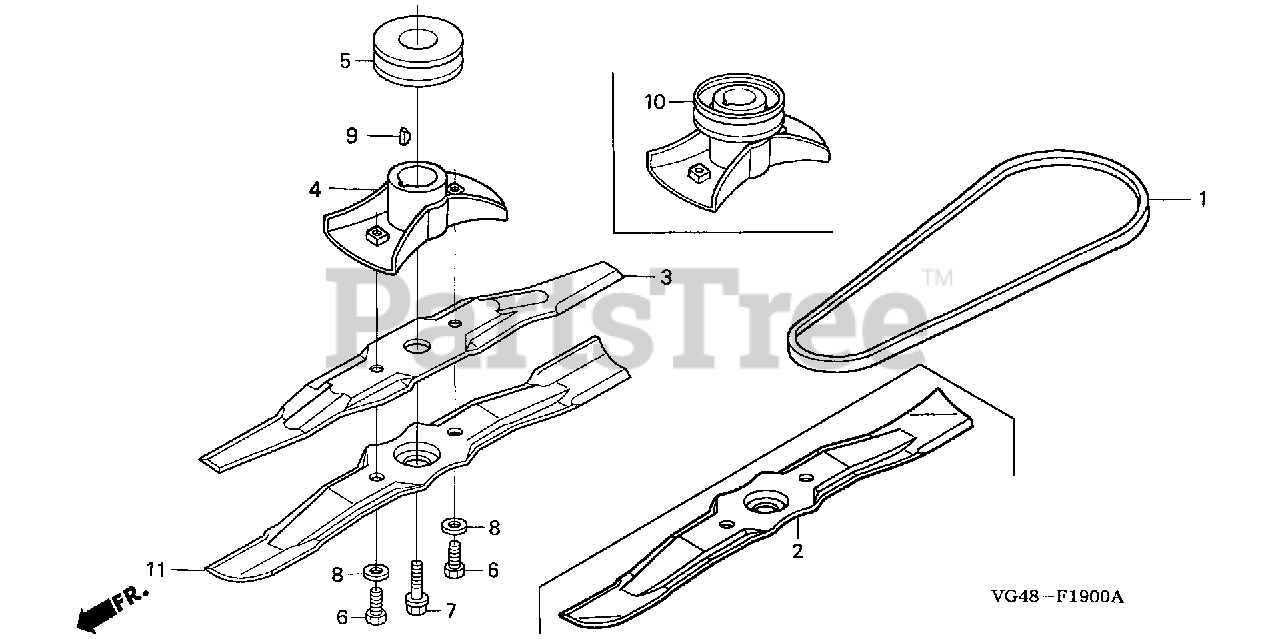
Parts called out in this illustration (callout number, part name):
1	V-BELT (3L-36.3)
2	BLADE, ROTARY (PCD=88MM)
3	BLADE, ROTARY (UPPER) (PCD=88MM)
4	KIT, BLADE HOLDER
4	HOLDER KIT, BLADE
5	PULLEY, DRIVE
6	BOLT, HEX. (10X20)
7	BOLT, FLANGE (3/8-24X1")
8	WASHER, SPRING (10MM)
9	KEY, WOODRUFF (3/16X5/8)
10	HOLDER, BLADE
11	BLADE, ROTARY
